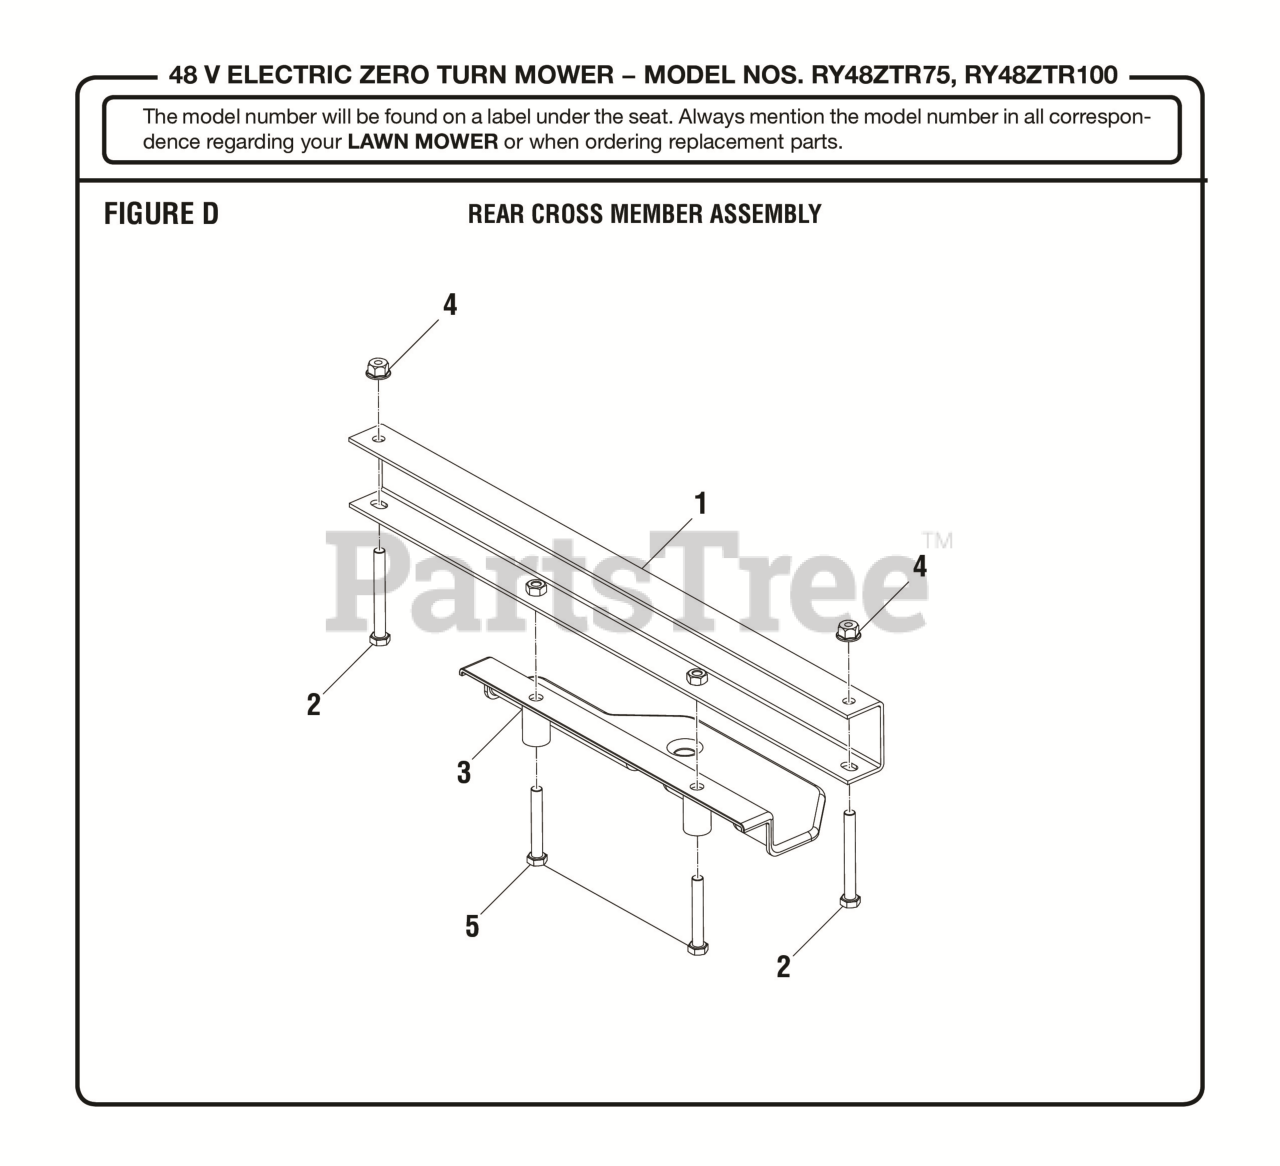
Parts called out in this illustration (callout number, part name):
1	Rear Cross Member, Frame
2	Bolt (M8 x 70 mm, Hex Hd.)
3	Tow Hitch
4	Flange Nut (M8) (For Drive Motor Controller V)
5	Bolt (M8 x 55 mm, Hex Hd.)
